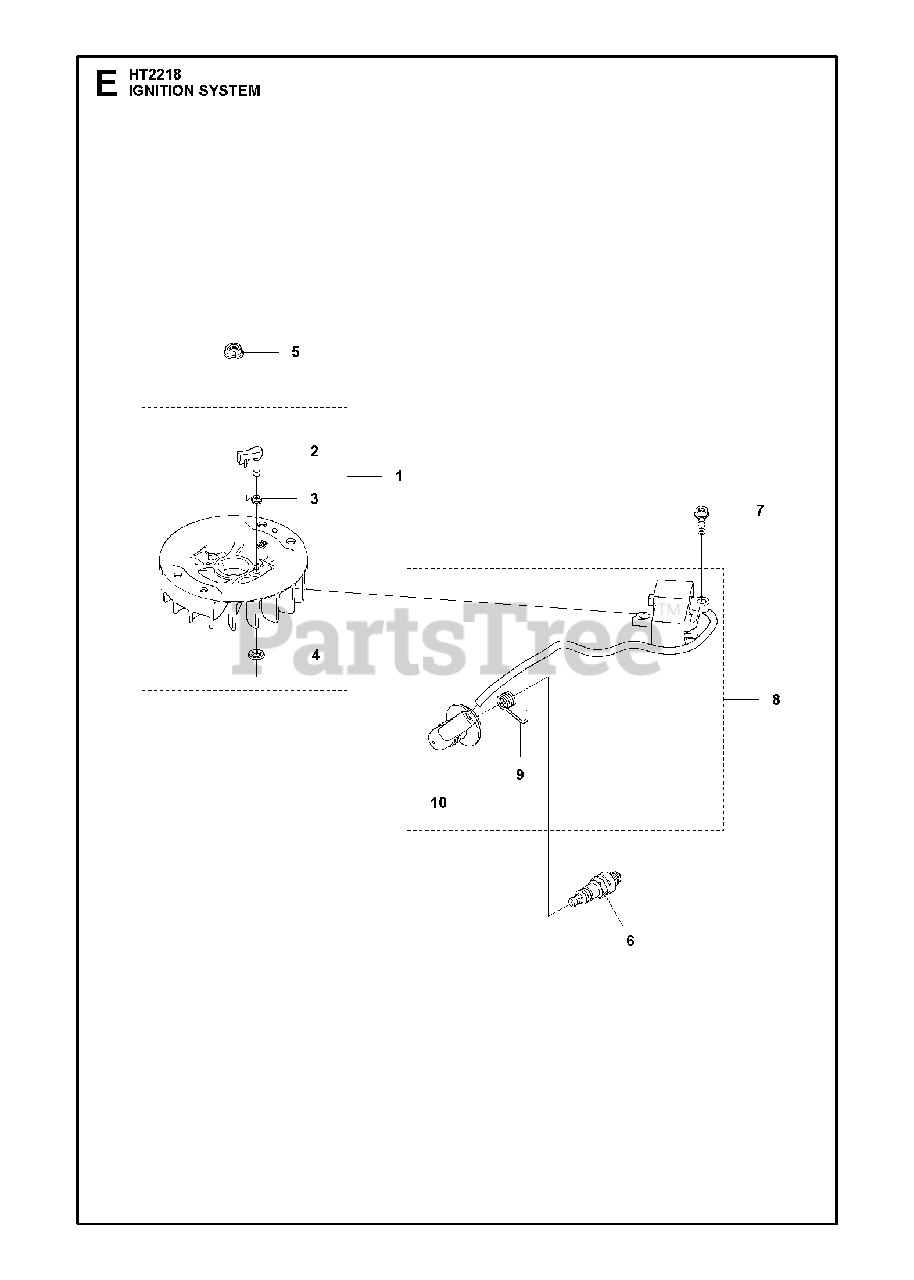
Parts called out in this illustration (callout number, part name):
2	STARTER PAWL
3	SPRING
4	LOCK WASHER
5	FLANGE NUT
6	SPARK PLUG RESISTOR NGK CMR6A
8	IGNITION MODULE
9	SPRING
10	CAP SPARK PLUG
